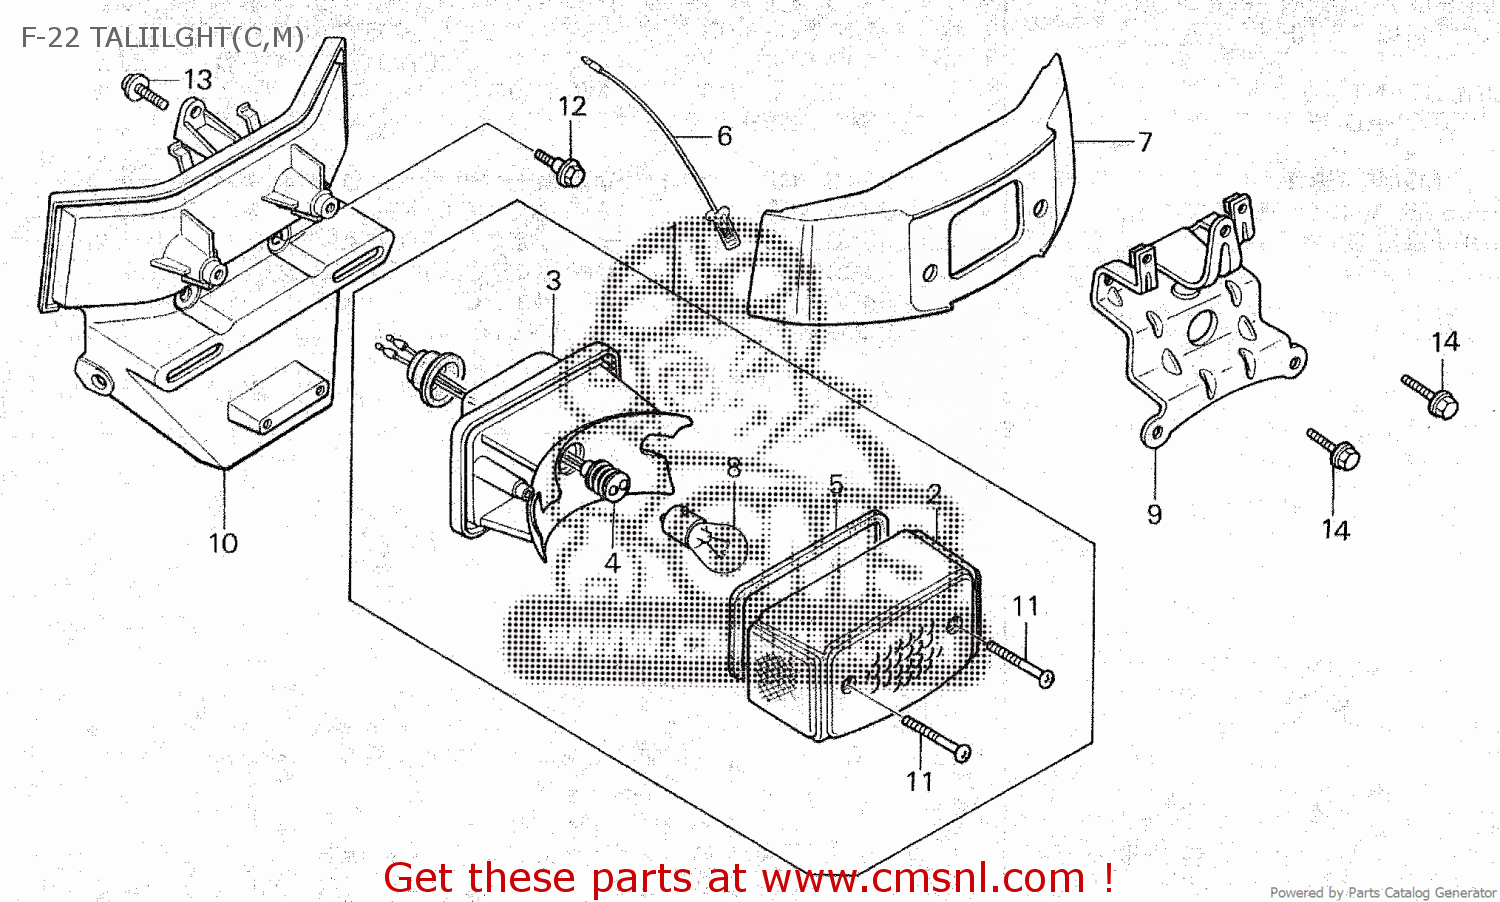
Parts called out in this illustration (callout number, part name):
1	TAILLIGHT UNIT
2	LENS,TAIL LIGHT
3	SOCKET,TAIL LIGHT
4	CORD,TAIL LIGHT
5	PKG,TAILLIGHT LEN
6	WIRE, GROUND
7	COVER *PB109*
8	BULB,TAIL LIGHT
9	STAY,TAILLIGHT
10	BRKT,NO
11	SCREW,TAP 4X40
12	BOLT,FLANGE,6MM
13	BOLT WASHER 5X20
14	BOLT, FLANGE,6X12
